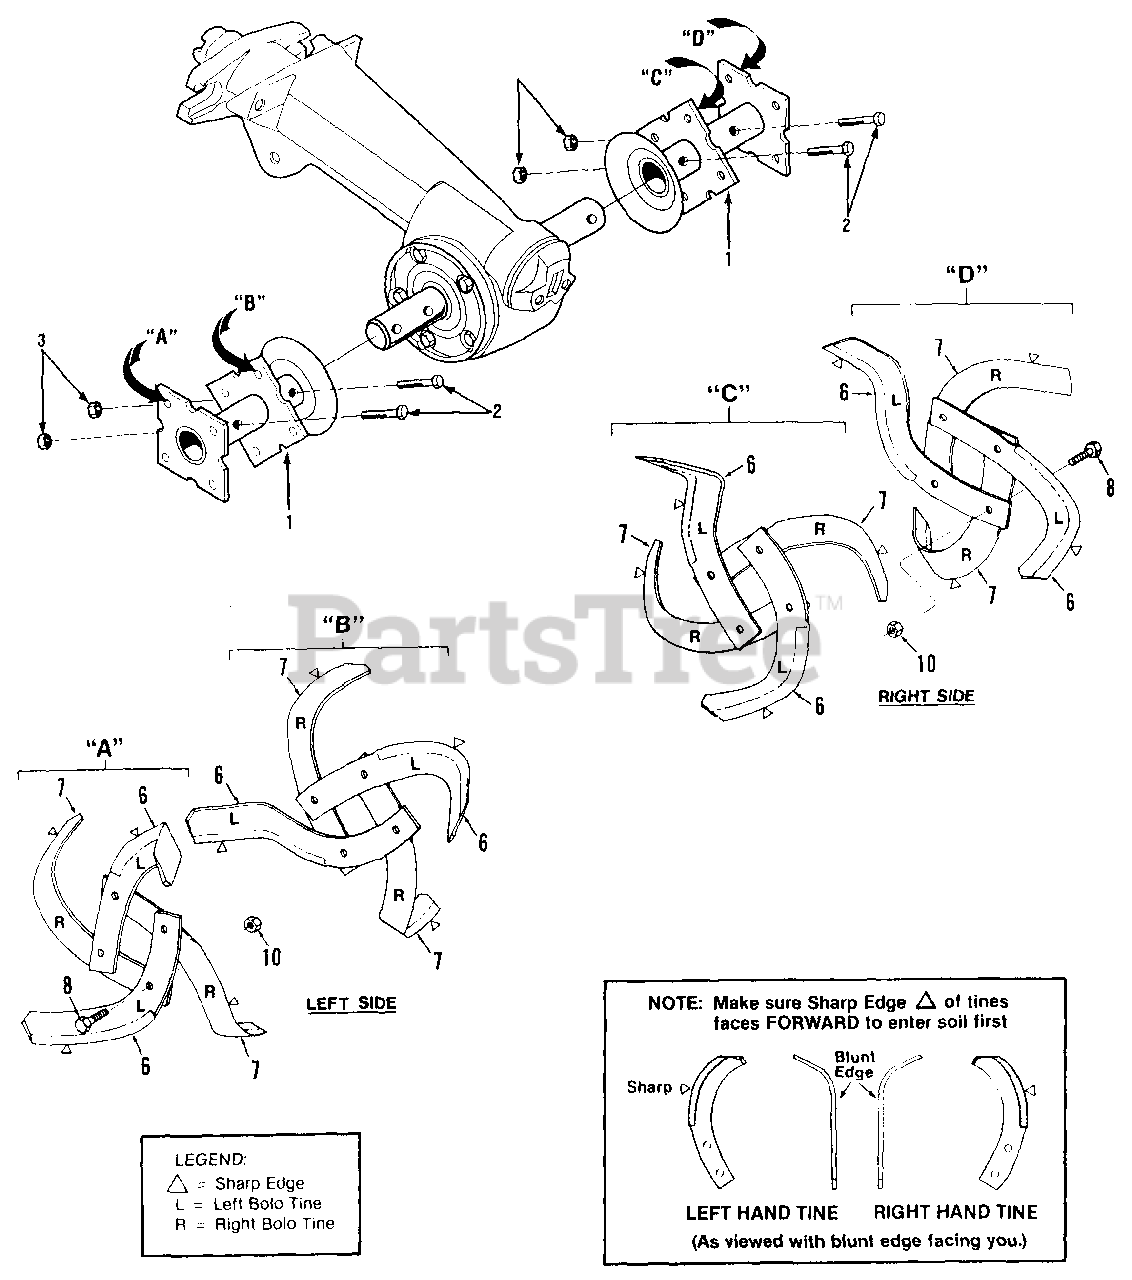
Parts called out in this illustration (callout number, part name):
1	Tine Holder-welded steel, fits left or right sides
2	Bolt-hex hd., 3/8-16 x 2"
6	Bolo Tine-single, left hand.
7	Bolo Tine-single, right hand.
8	Bolt-hex hd., 3/8-16 x 1"
10	Locknut-hex, 3/8"-16
